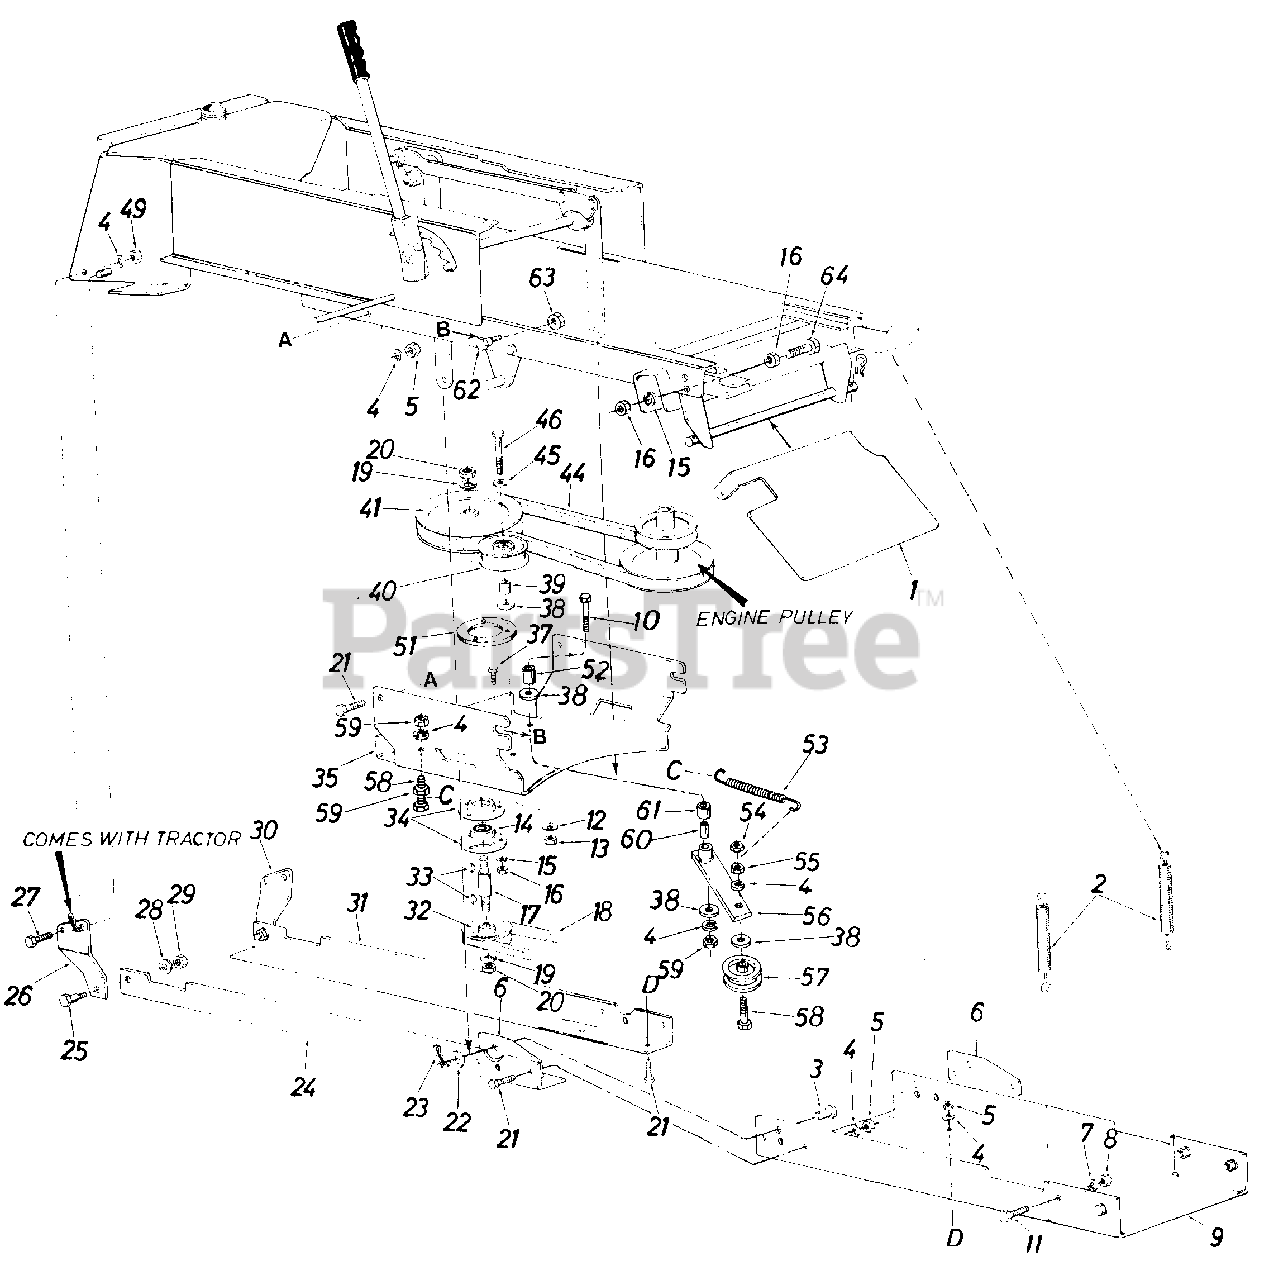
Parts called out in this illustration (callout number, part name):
1	Guide Bracket
2	Helper Spring
3	Clevis Pin
4	L.-Wash. 3/8" I.D.
5	Hex L.-Nut3/8-24Thd.
6	Attaching Plate
7	L.-Wash. 1/2" I.D.
8	Hex L.-Nut 1/2-20Thd.
9	Front Support Channel
10	Hex Bolt 3/8-1 6 x 3. 75 " Lg.
11	Hex Bolt 1/2-20x 1.25" Lg.
12	Belleville Wash. 3/8" I.D.
13	Hex L.-Nut 3/8-16 Thd.
14	Ball Bearing
15	L.-Wash. 5/16" I.D.
16	Hex Nut 5/16-18 Thd.
17	Spindle
18	"V"-Belt 1/2" x88"x 2 (Kevlar)
19	L.-Wash. 5/8" I.D.
20	Hex Jam Nut 5/8-11 Thd.
21	Hex Bolt 3/8-24 x 1.00" Lg.
22	Flat Washer
23	Internal Cotter Pin
28	Fl.-Wash. .44" I.D. x 1.38" O.D. x .130
29	Hex L.-Nut 7/16-24 Thd.
30	Rear Hanger Brkt.-L.H.
33	#6 Hi-Pro Key 3/16 x 5/8" Dia.
34	Bearing Housing
35	Supporting Bracket
37	Hex Sems Bolt 5/16-18 x 1.00" Lg.
38	Fl.-Wash. .38" I.D. x 1.00" O.D. x .135
39	Spacer.38" I.D. x .62" O.D.
40	Fl.-Idler Pulley
41	Upper Drive Pulley
44	"V"-Belt 1/2" x 49.8" Lg.
45	Fl.-Wash.
46	Hex Bolt 3/8-16 x 2.50" Lg.
49	Hex Nut 3/8-16 Thd.
53	Extension Spring .54" O.D. x 5.25" Lg.
54	Hex Cent. L.-Nut 3/8-16 Thd.
55	Hex Jam Nut 5/8-11 Thd.
56	Idler Arm Ass'y.
57	Idler Pulley
58	Hex Bolt 3/8-16 x 2.25" Lg.
59	Hex Jam Nut 3/8-16 Thd.
60	Spacer .377" I.D. x .60" O.D. x.830" Lg.
61	Spacer .380" I.D. x .630" O.D. x.565" Lg.
62	Shoulder Bolt .498 Dia. x .340
63	Hex Cent. L.-Nut 3/8-16 Thd.
64	Hex Bolt 5/16-18 xl.50" Lg.
